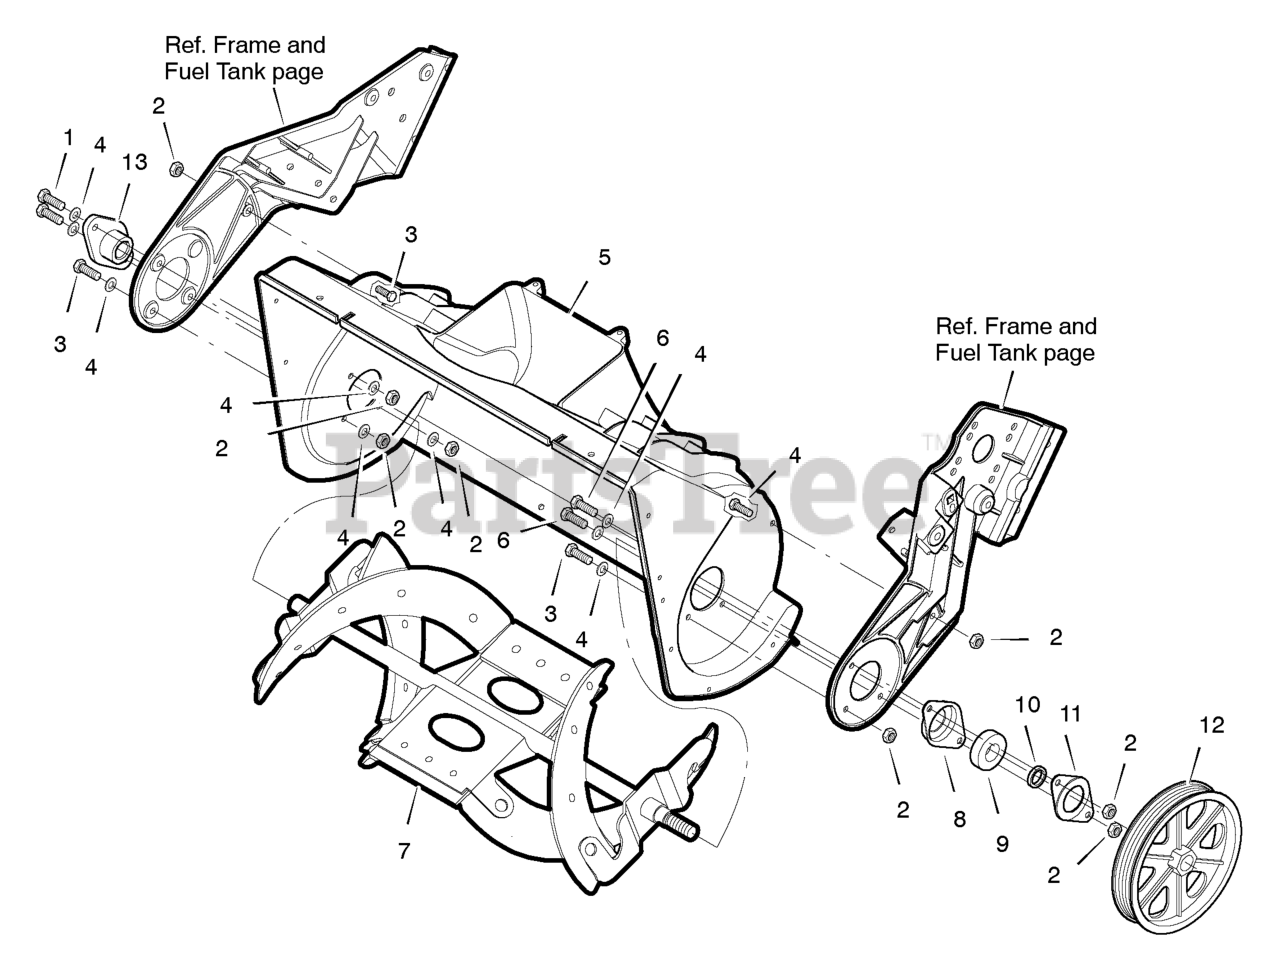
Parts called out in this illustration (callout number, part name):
1	Screw, 1/4-20 x 1.00
2	Nut, Hex 1/4-20
3	Screw, 1/4-20 x .75
4	Washer, Flat
5	Housing Assembly, Auger
6	Screw, 1/4-20 x .63
7	Auger Assembly, 22"
8	Retainer, Bearing
9	Bearing
10	Sleeve, Spacer
11	Plate, Bearing Retainer
12	Pulley, Auger Drive V6
13	Bearing, Flange
